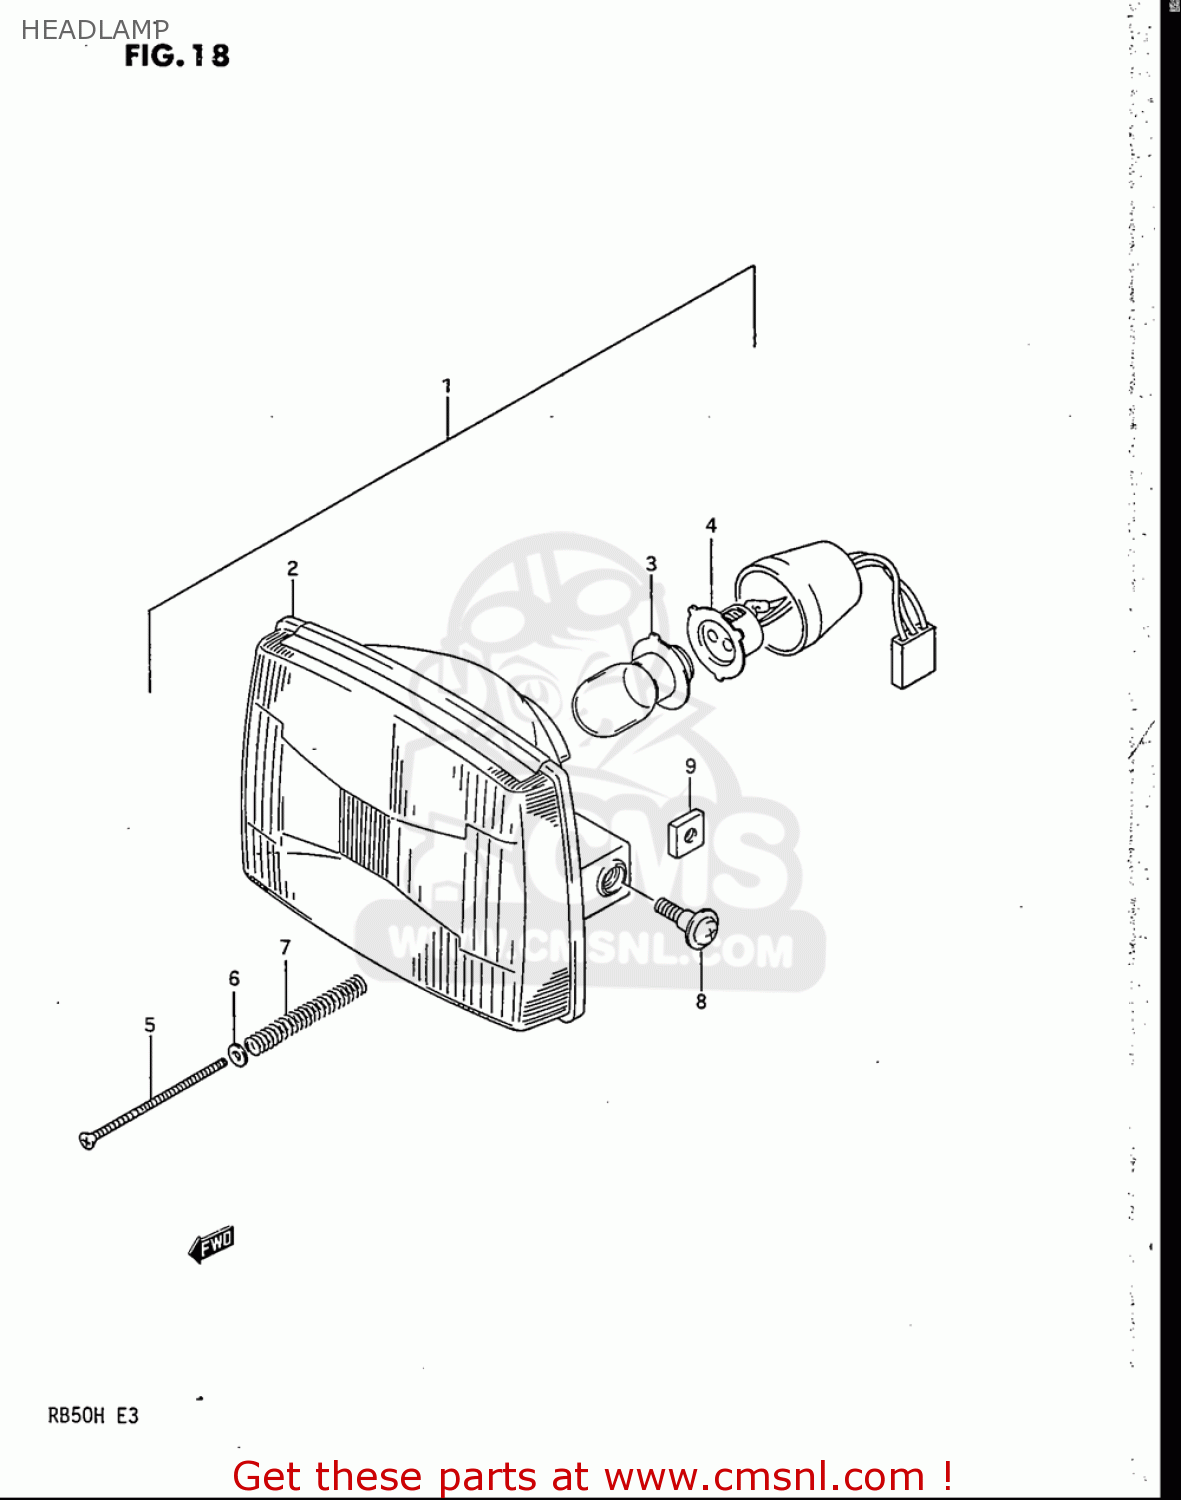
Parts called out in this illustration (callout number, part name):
2	LAMP,UNIT
3	BULB
4	SOCKET
6	WASHER
8	SCREW
9	NUT
